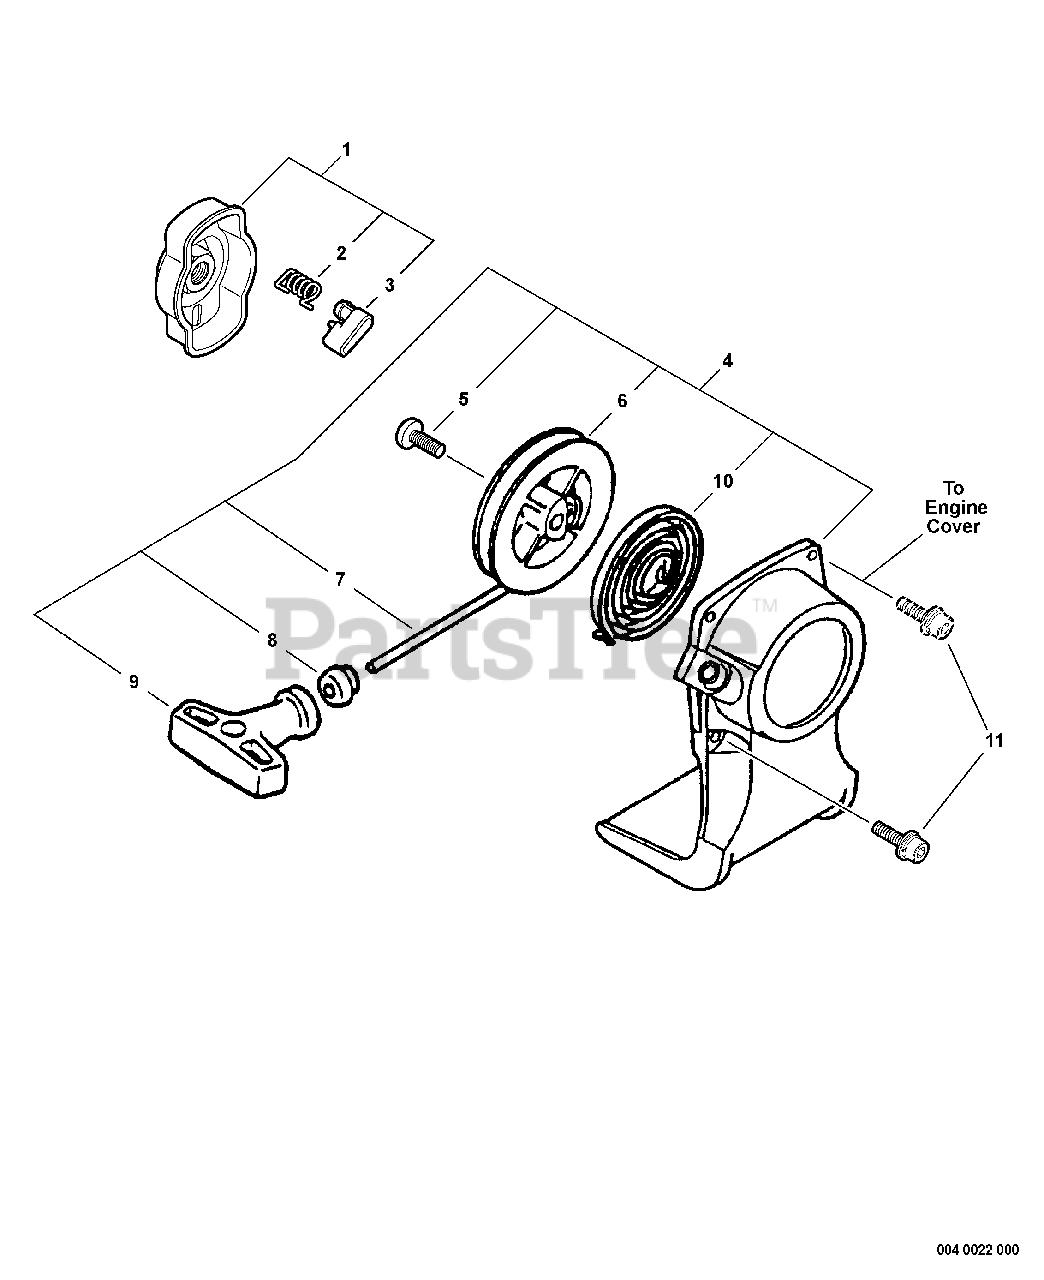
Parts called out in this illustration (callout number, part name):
1	STARTER PAWL ASSY
2	SPRING, RETURN
3	PAWL, STARTER - BLACK
4	STARTER ASSY
6	REEL, ROPE
7	ROPE, STARTER - 3X1000
8	GUIDE, ROPE
9	GRIP, STARTER
10	SPRING, REWIND
11	SCREW - 4X16
